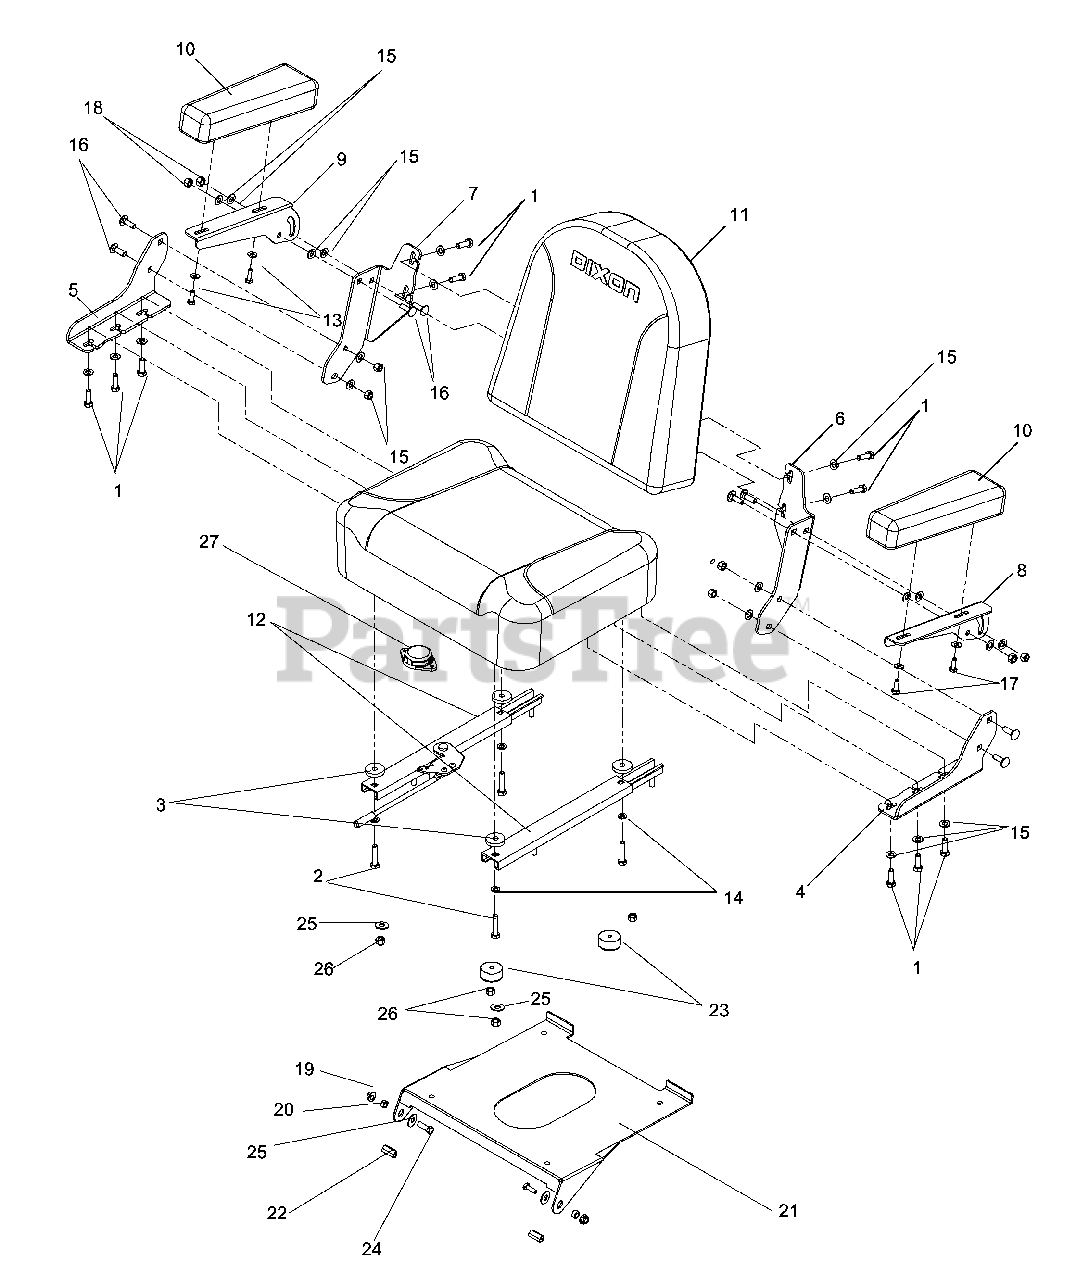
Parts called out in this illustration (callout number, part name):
1	5/16-18X1 HHB G5W/NY
2	5/16-18X1-1/2 HHB GR5WNY
3	WASHER NYLON
4	SEAT BOTTOM BRKT LH
5	SEAT BOTTOM BRKT RH
6	SEAT BACK BRKT LH
7	SEAT BACK BRKT RH
8	ARM REST BRACKET LH
9	ARM REST BRACKET RH
10	ARMREST
11	SEAT BACK
12	SEAT SLIDE (SET)
13	WASHER 1/4 SAE
14	WASHER 5/16 LOCK
15	FLAT WASHER 5/16 SAE
16	RHSNB 5/16C X 1
17	HCS 1/4C X 3/4 HCS
18	NUT 5/16 NYLOC
19	5/16-18 FLANGED L-NUT
21	SEAT PLATE
22	CLIP-1.06
23	ISO MOUNT
24	HCS 5/16C X 3/4
25	FLAT WASHER 5/16 SAE
26	NUT 5/16 NYLOC
27	SEAT SWITCH MILSCO
